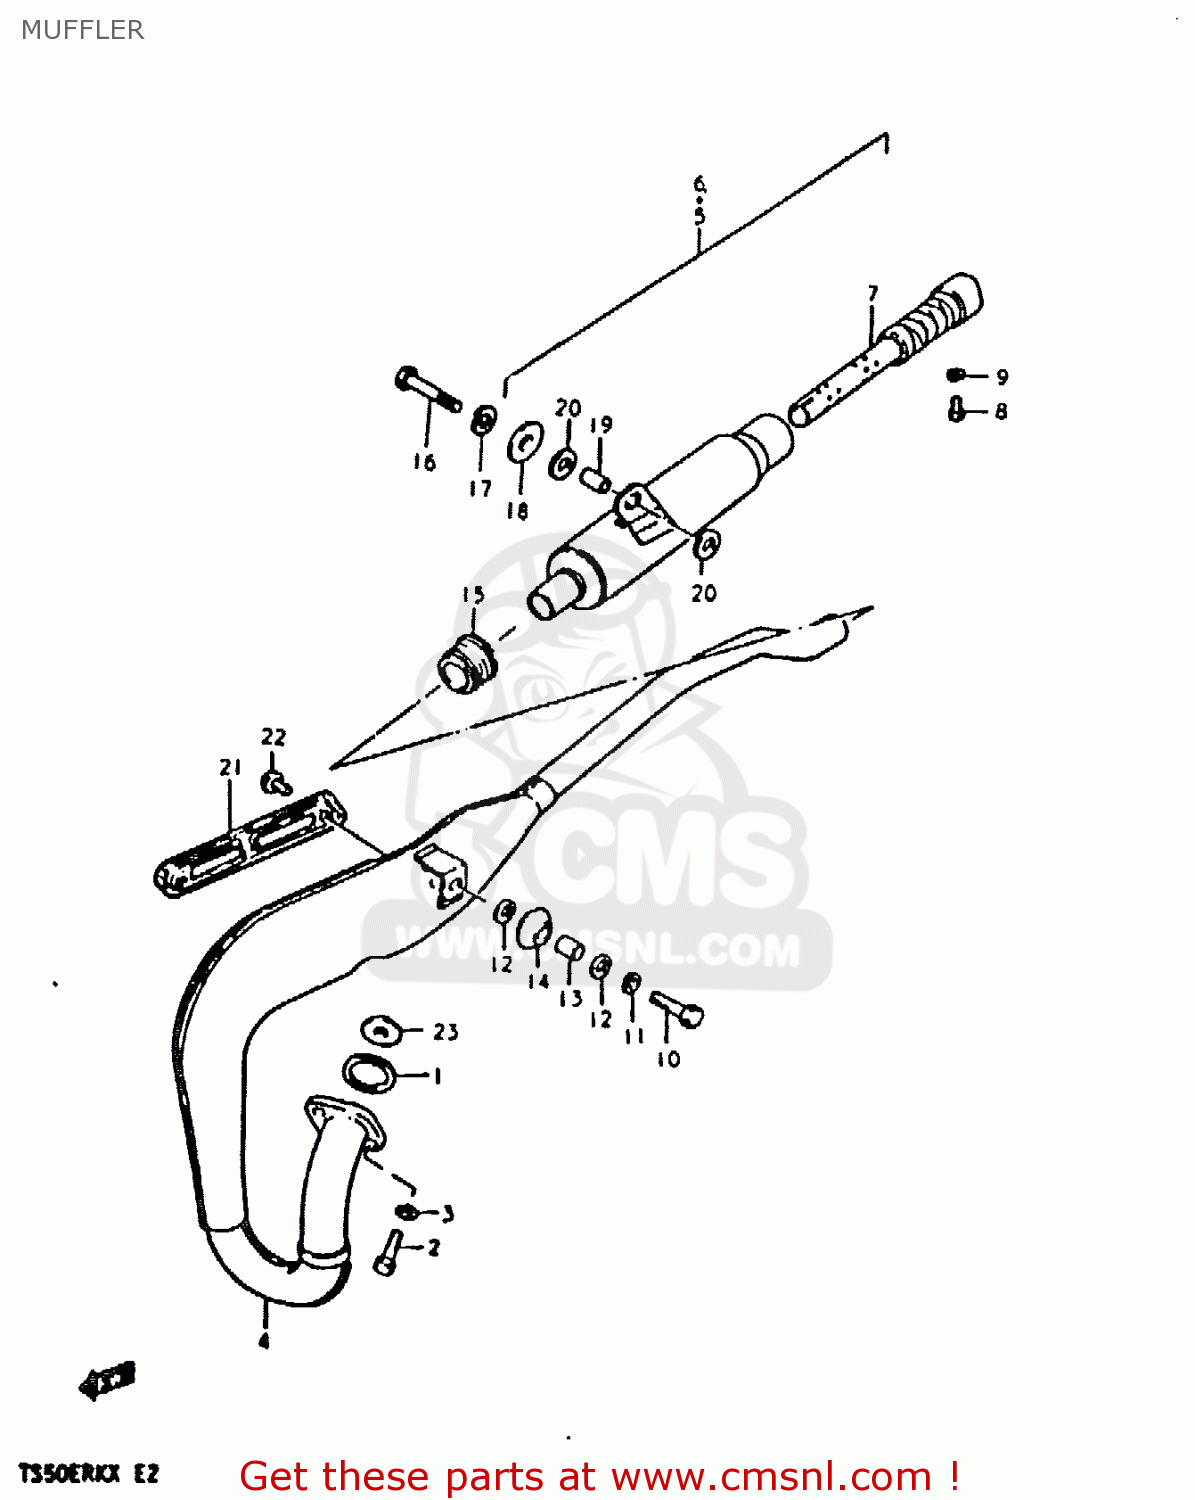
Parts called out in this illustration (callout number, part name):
1	GASKET,EXHAUST PIPE (NAS)
2	BOLT
3	LOCK WASHER
4	MUFFLER, 1ST
5	MUFFLER, 2ND
7	PIPE, BAFFLE
8	BOLT(5X8)
9	LOCK WASHER
10	BOLT (8X30)
11	LOCK WASHER
12	WASHER
13	SPACER (8X12X15)
14	DAMPER,MUFFLER,FR
15	CONNECTOR,MUFFLER
16	BOLT
17	LOCK WASHER
18	WASHER
19	SPACER (8.6X13.8X9)
20	CUSHION
21	COVER,MUFFLER
22	SCREW
